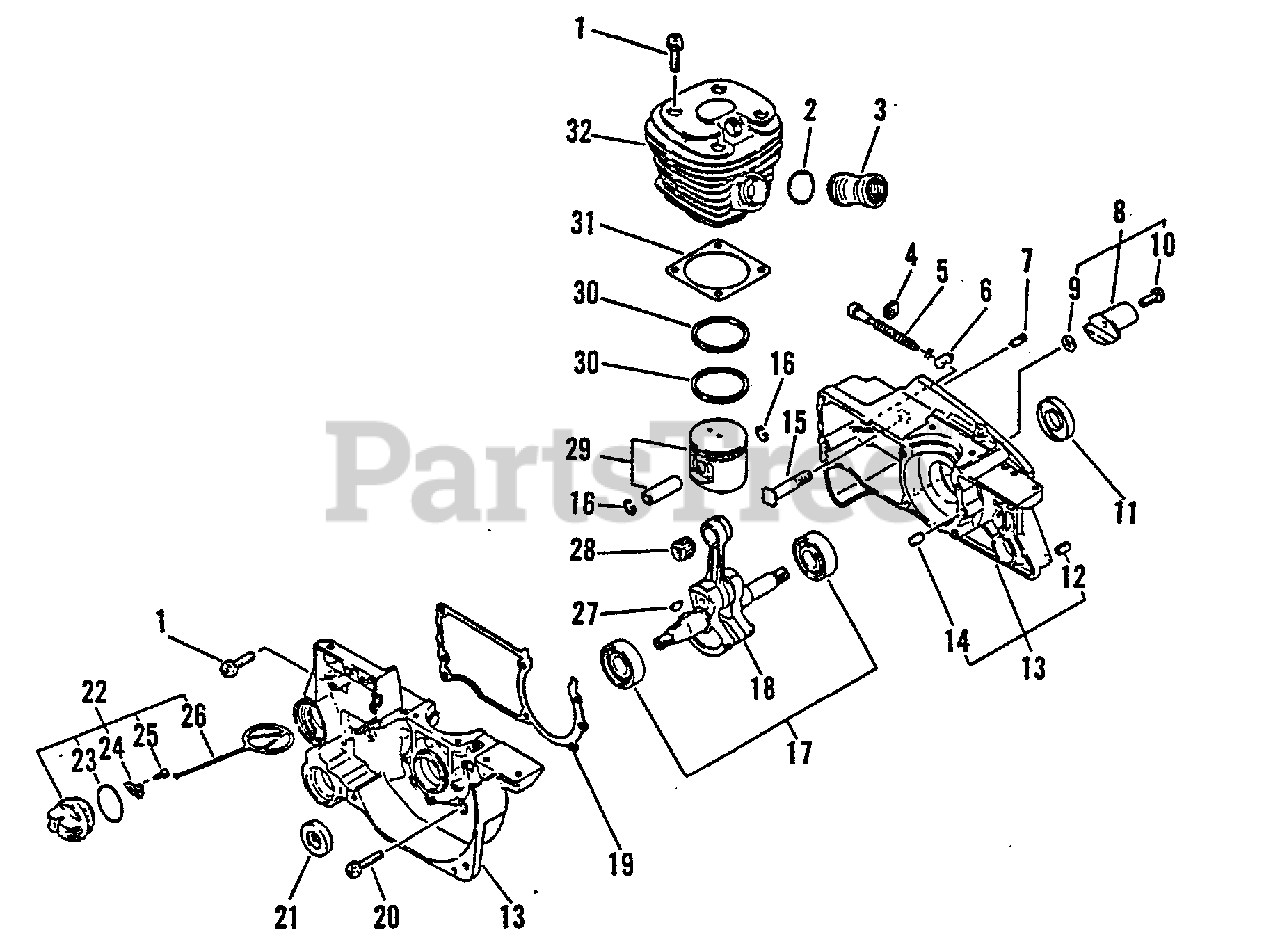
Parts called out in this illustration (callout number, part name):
1	BOLT 5×20
2	BAND
3	ADAPTOR, INTAKE
5	SCREW, CHAIN TENSION
6	TENSIONER, CHAIN
7	VENT ASSY
8	CHAIN CATCHER KIT
9	WASHER, FLAT 5.5×10×0.8
10	SCREW 5×18
11	SEAL, OIL
12	PIN, SPRING 5×10
13	CRANKCASE KIT
14	PIN, LOCATING 5×10
15	STUD, GUIDE BAR 8
16	RING, SNAP 8
17	BEARING SET
18	CRANKSHAFT ASSY
19	GASKET, CRANKCASE
20	BOLT 5×30
21	SEAL, OIL
22	CAP ASSY
24	RETAINER, CONNECTOR
25	SCREW, TAPPING 3×8
26	CONNECTOR, CAP L= 60 MM
27	KEY, WOODRUFF
28	BEARING, NEEDLE
29	PISTON KIT
30	RING, PISTON
31	GASKET, CYLINDER
32	CYLINDER KIT
